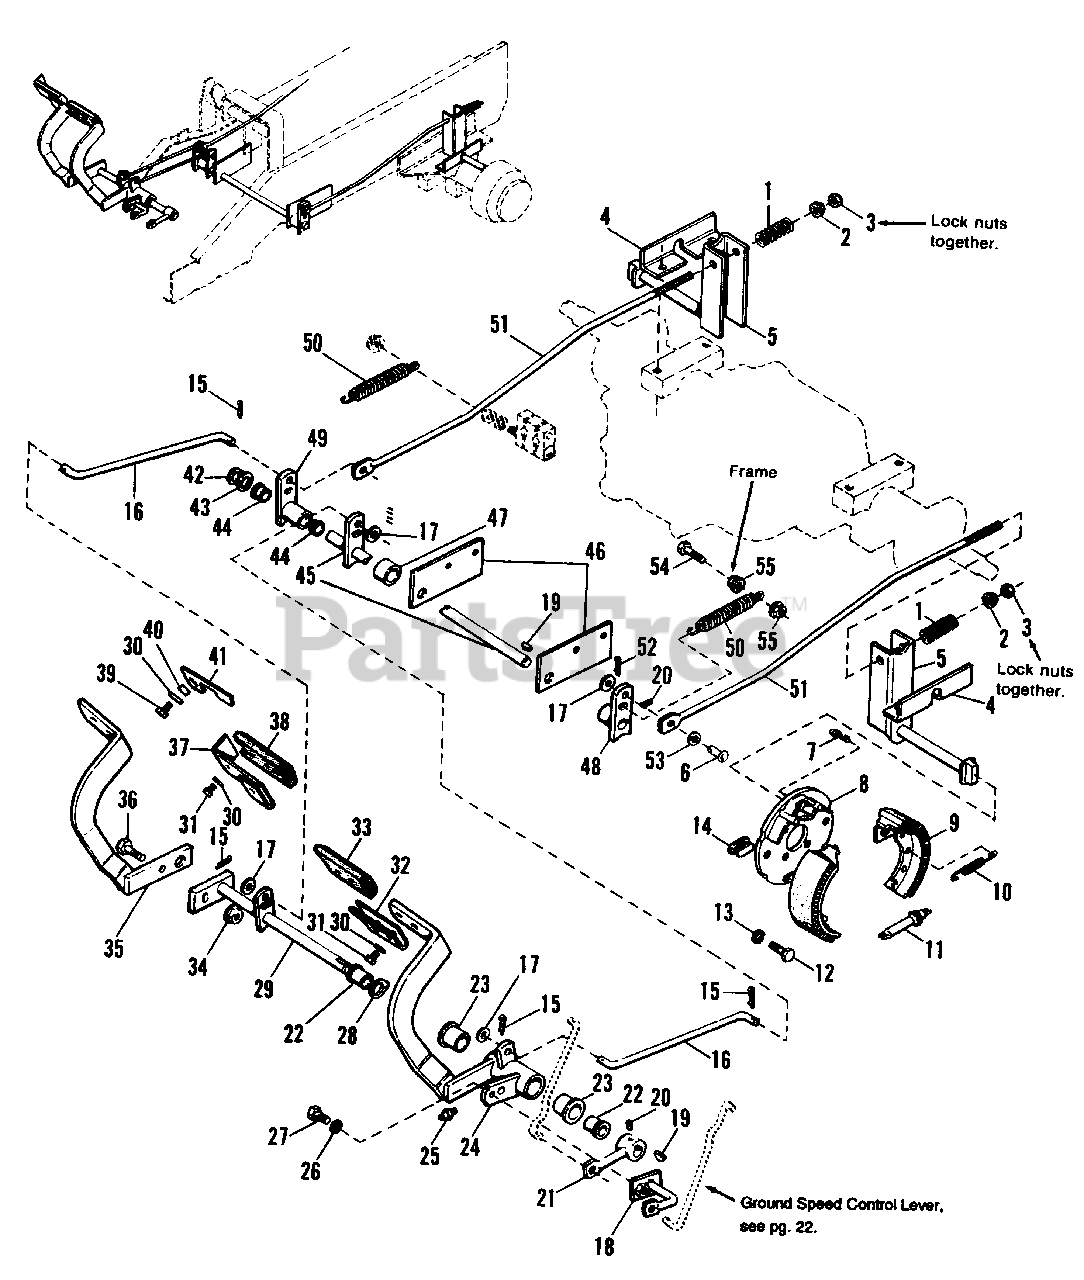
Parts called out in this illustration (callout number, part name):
1	SPRING, Compression
2	NUT, Large Flange, 1/2-13
3	NUT, Hex, 1/2-13
4	SUPPORT, Actuator
5	ACTUATOR ASSY.
7	SPRING, Extension
8	BRAKE SUPPORT ASSY.
9	BRAKE SHOE & PAD ASSY.
10	SPRING, Extension
11	SCREW ASSY., Brake Adjusting
12	CAPSCREW, Hex Hd, 3/8-16 x 1
13	LOCKWASHER, 3/8
15	PIN, Cotter, 1/8-3/4
16	ROD & PLATE, Brake
17	WASHER, Plain, 13/32 x 7/8 x 5/64
18	ROD ASSY., Lock
19	KEY, Woodruff #9
20	SETSCREW, Sq. Hd., 5/16-18 x 1/2
21	ROD ASSY., Pivot Plate
22	BUSHING, 3/4 x 7/8 x 1
23	BUSHING, 1-1/4 x 1-3/4 x 1
24	LEVER ASSY., Brake, LH.
25	FITTING Lube, 1/4 " Drive
26	LOCKWASHER, 5/16
27	CAPSCREW, Hex Hd.
28	RING, Retaining
29	SHAFT ASSY., Brake, R.H.
30	LOCKWASHER, 1/4
31	CAPSCREW, Hex Hd., 1/4-20 x 3/4
32	SUPPORT, Lock
33	PAD, Pedal, Inner
34	LOCKNUT, Hex, Whiz, 7/16-14
35	LEVER ASSY., Brake, R.H.
36	CAPSCREW, Hex Hd., 7/16-14 x 1-1/4
37	SUPPORT, Pedal Lock
39	CAPSCREW, Hex Hd., 1/4-20 x 1
41	LOCK, Pedal
42	RING, Retaining
43	WASHER, Plain, 3/4
45	SHAFT & LEVER ASSY., Brake Pivot
46	SUPPORT, Brake Cross Shaft
47	SPACER, Special
48	LEVER ASSY., Brake
49	LEVER ASSY., Brake
50	SPRING, Extension
51	ROD ASSY., (Incl. Ref. Nos. 6 & 53)
52	PIN, Cotter, 1/8 x 3/4
53	WASHER, 13/32
54	CAPSCREW, Hex, 5/16-18 x 1-1/4
55	NUT, Hex Flangelock, 5/16-18
